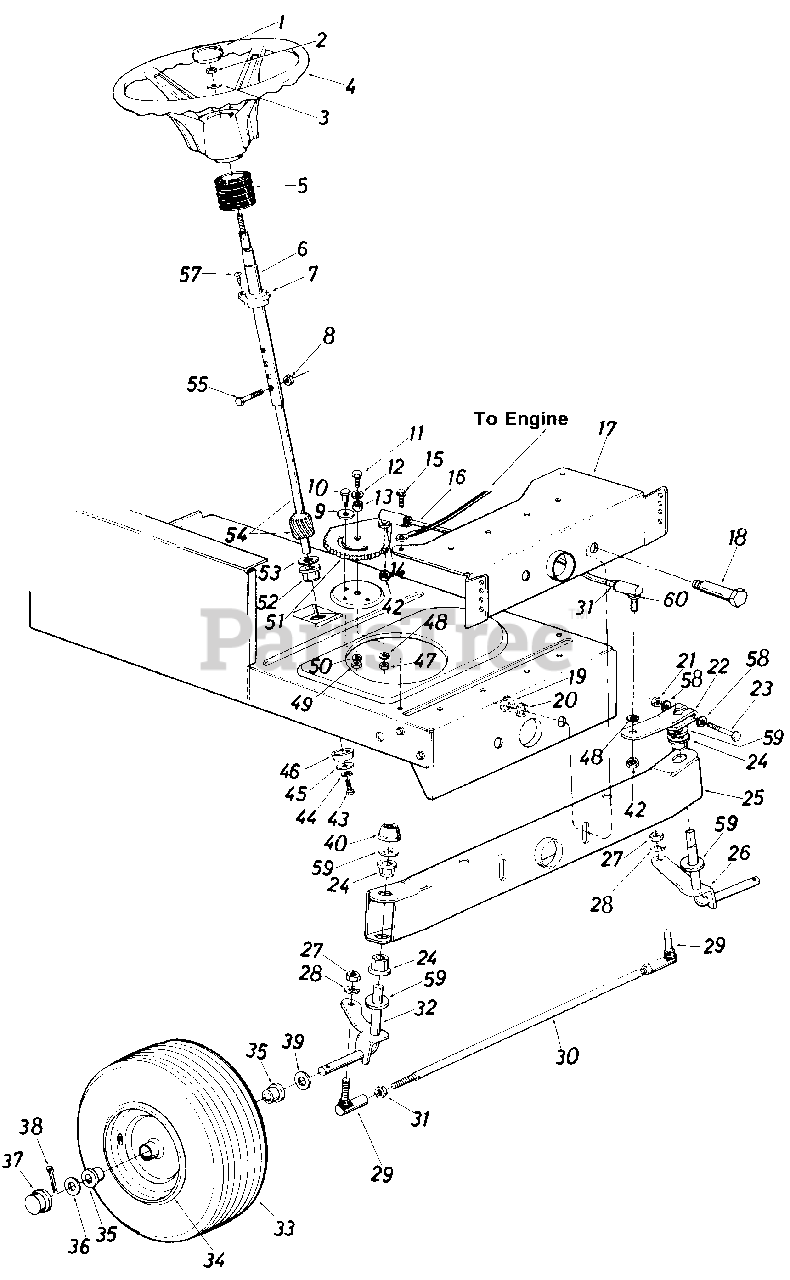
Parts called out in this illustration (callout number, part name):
1	Steering Wheel Cap
2	Hex L-Nut 5/16-24 Thd.
3	Belleville Wash. .345" I.D.
4	Steering Wheel
5	Steering Bellow 4.5"
6	Steering Column Ass'y.
7	Flange Bearing .890 I.D. x 1.36 O.D.
8	Hex L-Nut 1/4-20 Thd.
9	Fl-Wash. .438" I.D. x 1.37 O.D.
10	Shoulder Bolt .437" Dia. x .35 Lg. 5/16-18 Thd.
11	Hex Bolt 3/8-24 x 1.0 Lg. (Grade 5)
12	Bell-Wash. .40" I.D. x 1.13" O.D.
13	Spacer .380" I.D. x .625" O.D. x .227
14	L-Wash. .38" I.D.
15	Hex Wash. Hd. Self-Tap Scr.
16	Steering Drag Link
17	Front Pivot Brkt.
18	Shoulder Bolt .498" Dia. x 2.04 Lg. 3/8-16 Thd.
19	Hex Nut 3/8-16 Thd.
20	L-Wash. 3/8" I.D.
21	Hex Cent. L-Nut 5/16-24 Thd.
22	Steering Arm Front Axle
23	Hex Bolt 5/16-24 x 2.00" Lg. (Grade 5)
24	Hex Flg. Brg. .634 I.D.
26	Front Axle Ass'y. L.H.
27	Hex Nut 3/8-24 Thd.
28	L-Wash. 3/8" I.D.
29	Ball Joint 3/8-24 Thd.
30	Tie Rod
31	Hex Jam Nut 3/8-24 Thd.
32	Front Axle Ass'y. R.H.
33	Wheel Ass'y. Comp.
34	Front Wheel Rim Only
35	Bearing
36	Fl-Wash. .635 I.D. x 1.59" O.D.
37	Front Wheel Hub Cap
38	Cotter Pin 1/8" Dia. x 1.25"
39	Fl-Wash. .640" I.D. x 1.24" O.D.
40	Push Cap 5/8" Dia. Rod
42	Hex Nut 3/8-24 Thd.
43	Hex L-Bolt 5/16-18 x .62"
44	L-Wash. 5/16" I.D.
45	Fl-Wash. .344" I.D. x 1.25" O.D.
46	Spacer (Plastic)
47	Hex Nut 3/8-24 Thd.
48	L-Wash. 3/8" I.D.
49	Hex Nut 5/16-18 Thd.
50	L-Wash. 5/16" I.D.
51	Steering Gear Segment
52	Hex Flg. Brg. .634 I.D.
53	Fl-Wash. (Hardened)
54	Steering Shaft Lower
55	Hex Bolt 1/4-20 x 1.31" Lg.
57	Oval Hd. Cr. Sunk Scr. #10 x 5/8" Lg.
58	Wave-Wash. .32" I.D. x .62" O.D.
59	Fl-Wash. (Hardened)
60	Drag Link Ball Joint 3/8-24 Thd.
